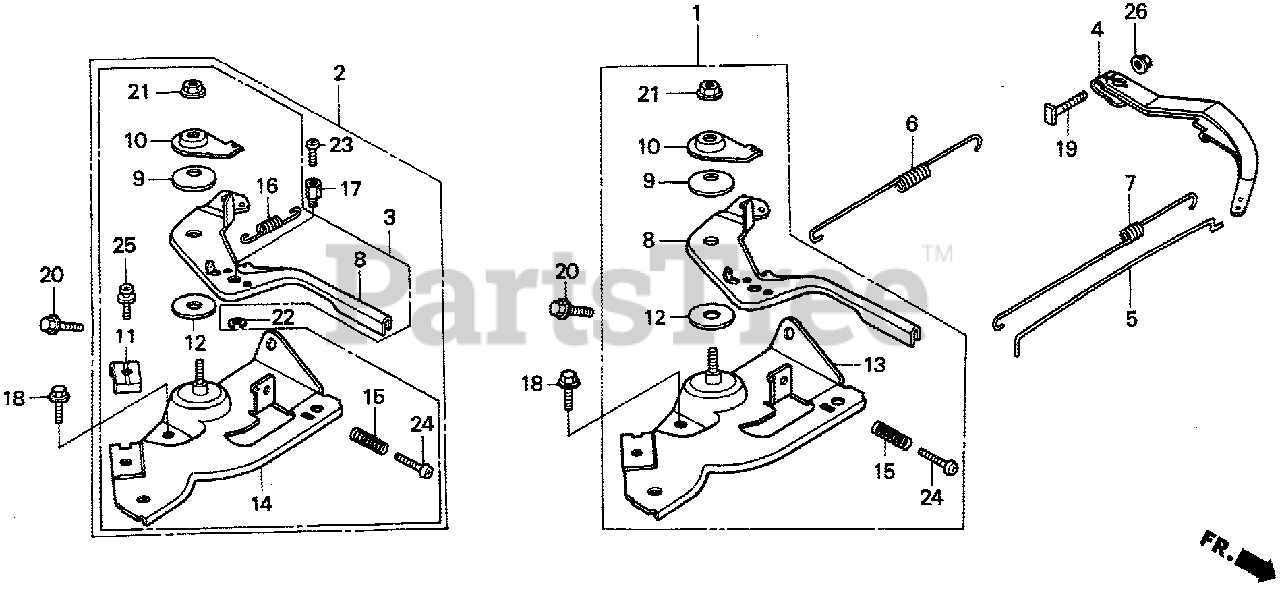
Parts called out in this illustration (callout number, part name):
2	CONTROL ASSY. (REMOTE)
4	ARM, GOVERNOR
5	ROD, GOVERNOR
6	SPRING, GOVERNOR
7	SPRING, THROTTLE RETURN
8	LEVER, CONTROL
9	SPRING, LEVER
10	WASHER, CONTROL LEVER
11	HOLDER, CABLE
12	SPACER, CONTROL LEVER
14	BASE, CONTROL
15	SPRING, CONTROL ADJUSTING
16	SPRING, CABLE RETURN
17	HOLDER, WIRE
18	BOLT, FLANGE (6X12) (CT200)
19	BOLT, GOVERNOR ARM
20	BOLT, FLANGE (6X20) (CT200)
21	NUT, SELF-LOCK (6MM)
22	CIRCLIP (5MM)
23	SCREW, PAN (4X6)
24	SCREW, PAN (5X25)
25	SCREW, PAN (5X16)
25	SCREW-WASHER (5X16)
26	NUT, FLANGE (6MM)
